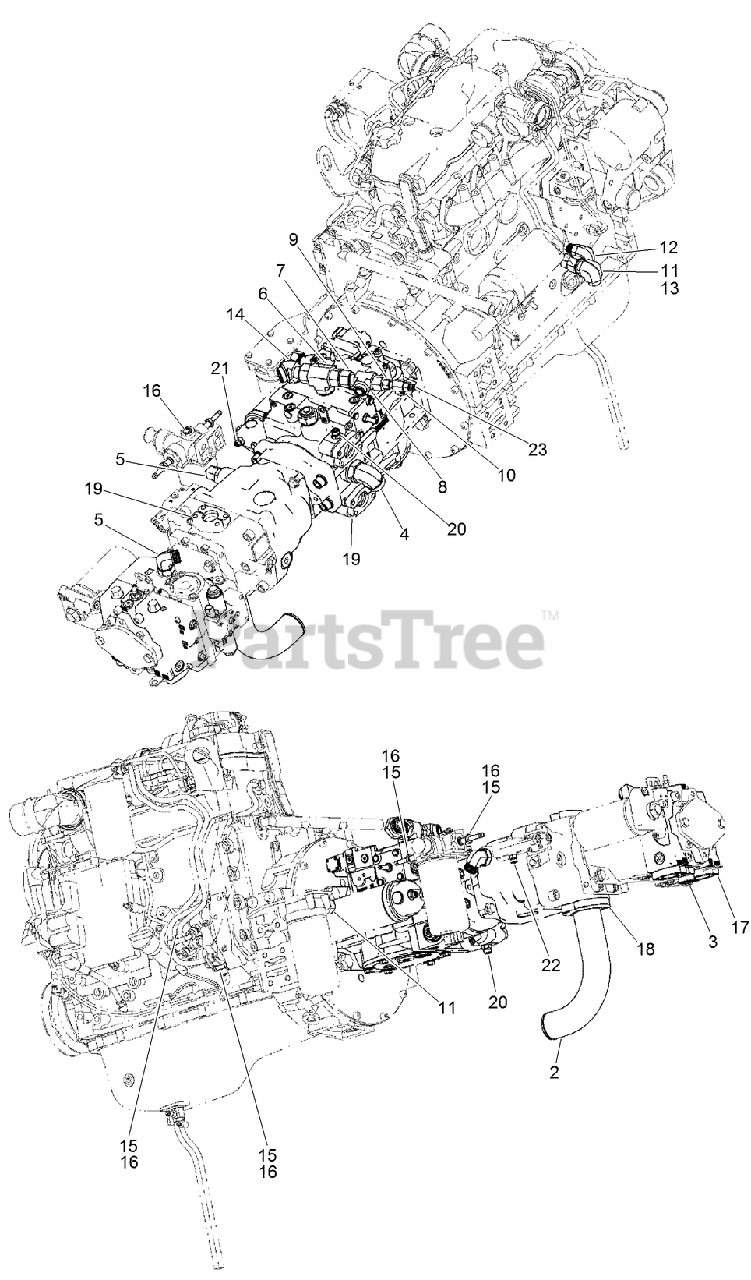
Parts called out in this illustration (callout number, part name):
2	TUBE-BENT
3	CONNECTION - Straight, -16 ORFS / -16 ORB
4	CONNECTION - 90 Deg, -20 ORFS / -20 ORB
5	CONNECTION - 90 Deg, -12 ORFS / -12 ORB
6	CONNECTION - Branch Tee, -16 ORFS / -16 ORB
7	FITTING-REDUCER
8	FITTING-TEE
9	FITTING-REDUCER
10	CONNECTION - Run Tee, -6 ORFS / -6 ORFS
11	CONNECTION - Straight, -12 ORFS / -10 ORB
12	CONNECTION - 90 Deg, -12 ORFS / -10 ORB
13	CONNECTION - 90 Deg, -12 ORFS / -12 ORFS
14	FITTING-ELBOW, 45
15	FITTING, FUEL HOSE BARB - M12 x 3/4 Hose ID
16	SEAL-FITTING, FUEL
17	KIT, SPLIT FLANGE -16 SAE, w/o Rings and Bolts
18	SPLIT FLANGE KIT
19	SPLIT FLANGE KIT
20	CONNECTION - Straight, -6 ORFS / -6 ORB
21	CONNECTION - Straight, -4 ORFS / -6 ORB
22	CONNECTION - Straight, -4 ORFS / -4 ORB
23	CONNECTION, REDUCER, -4 ORFS / -7 ORFS
